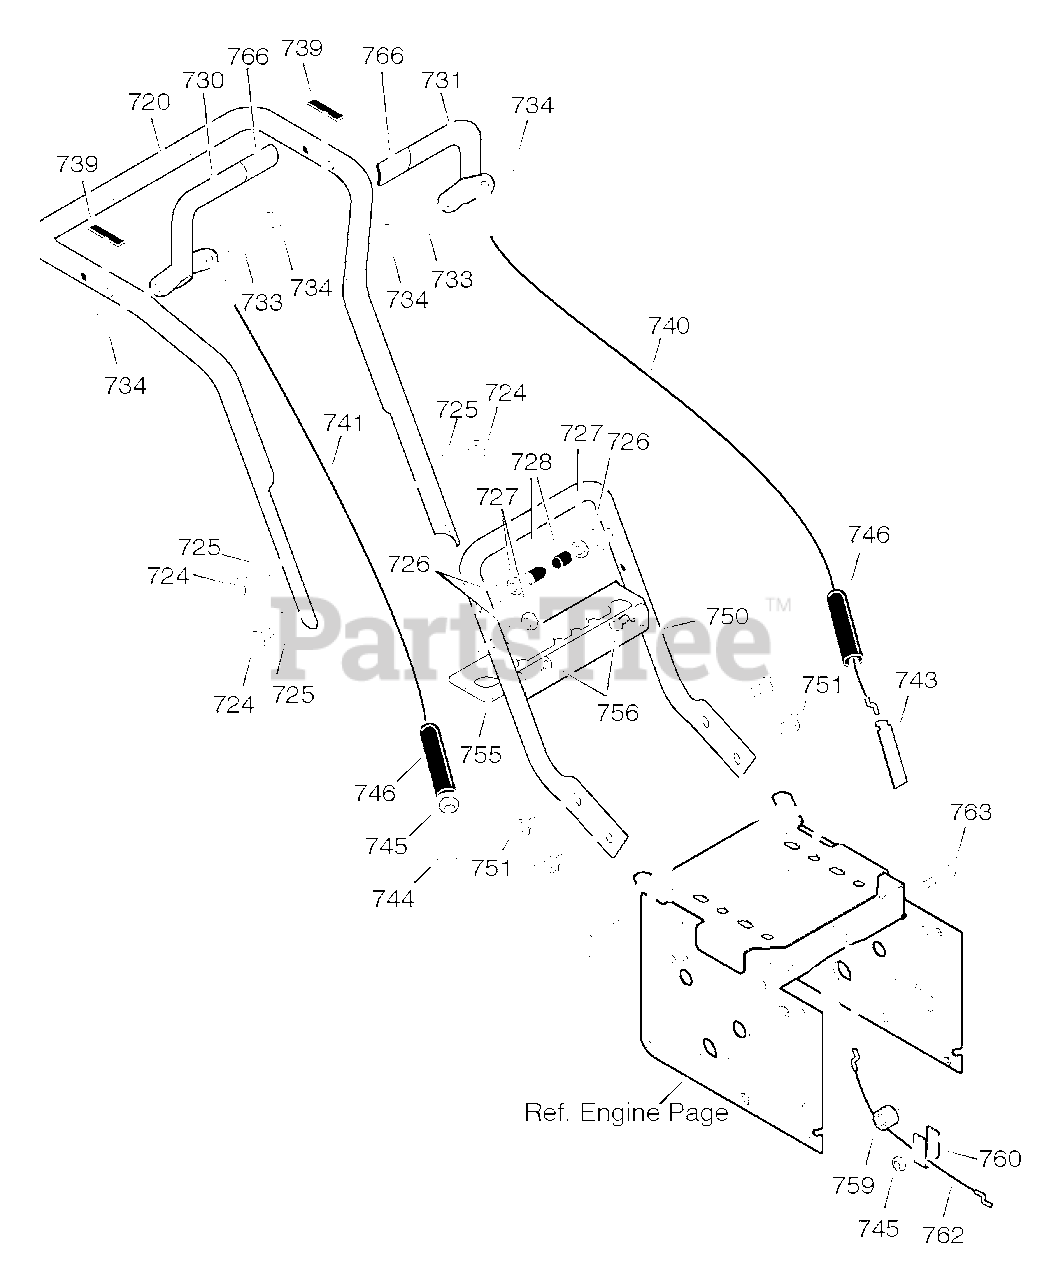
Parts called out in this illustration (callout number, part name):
720	HANDLE, UPPER
724	SCREW, 5/16-18 x 2.75
725	WASHER, FLAT
726	WASHER, SPTLK .31X.58X.08
727	NUT, 5/16-18 REGHEX
728	STOP, RED PLASTIC
730	CLUTCH HANDLE, RIGHT
731	CLUTCH HANDLE, LEFT
733	PIN, PIVOT CLUTCH
734	NUT, PUSH ON CAP
739	BUMPER, RECTANGLE
740	CABLE, CLUTCH 28.44L
741	CABLE, AUGER CLUTCH
743	BRACKET, CABLE ADJUSTER
744	SPRING, AUGER CLUTCH
745	NUT, 1/4-20
746	BOOT, CLUTCH SPRING
750	HANDLE, LOWER
751	SCREW, TAP 5/16-18 X .75
755	BRKT, GEAR SELECTOR
756	SCREW, 1/4-20 X 0.63
759	SPOOL-CABLE, AUGRT CLUTCH
760	BRACKET, CABLE SPOOL YZ
762	CABLE, LOWER DRIVE 12"
763	BOLT, HEX 1/4-20 X 1.50
